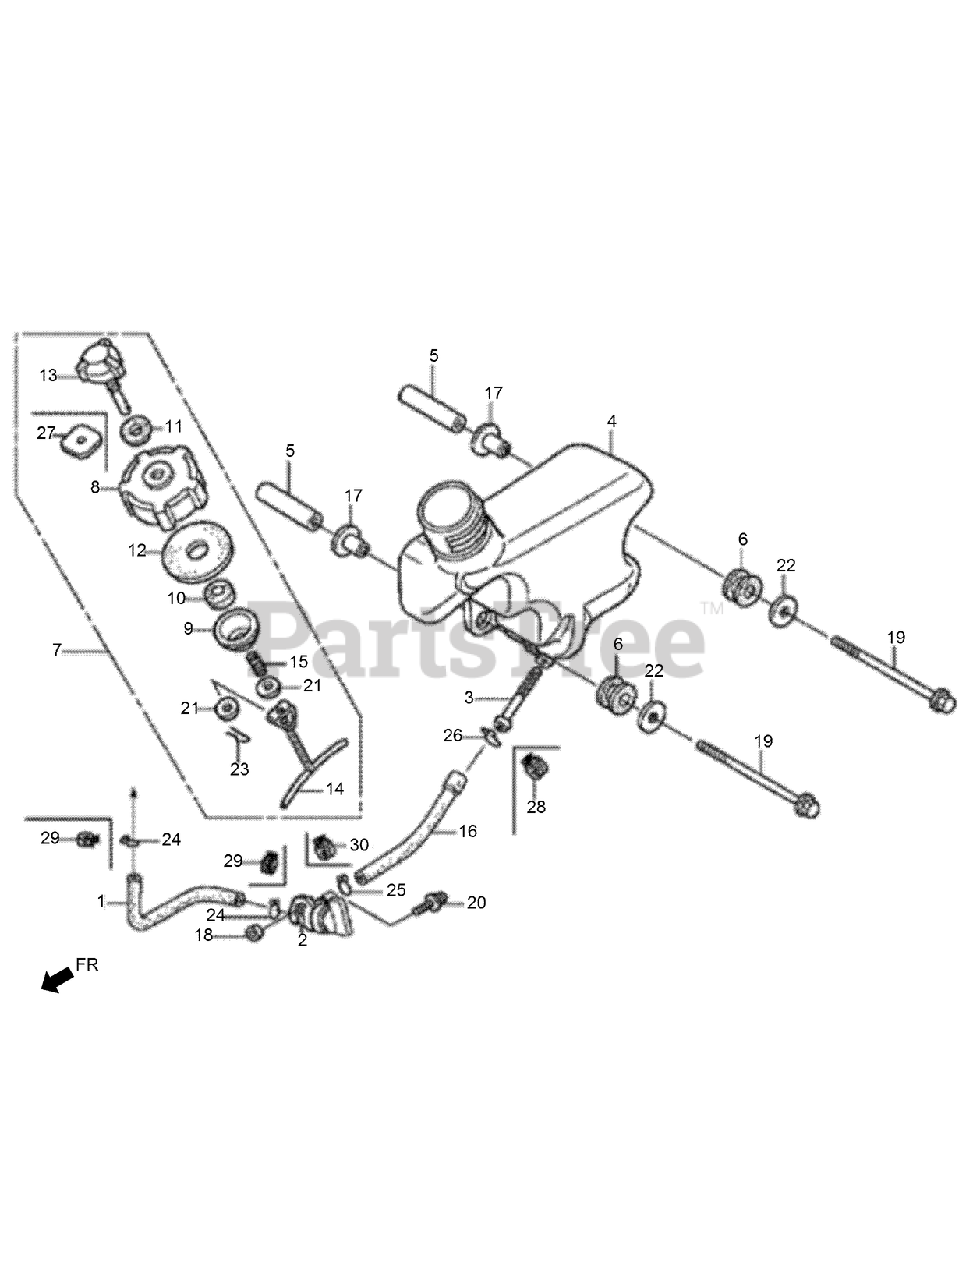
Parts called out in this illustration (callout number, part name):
1	TUBE B-FUEL
2	COCK ASM-FUEL
3	STRAINER-FUEL
4	TANK-FUEL
5	COLLAR-TANK SETTING
6	RUBBER A-TANK MOUNTING
7	CAP ASM-FUEL TANK
8	BODY-FUEL CAP
9	INNER-FUEL CAP
10	SPONGE-FUEL CAP BREATHER
11	PACKING-VALVE
12	PACKING-FUEL CAP
13	BREATHER VALVE ASM
14	LINK-FUEL CAP
15	SPRING-FUEL CAP
16	TUBE-FUEL
16	TUBE-FUEL TANK
17	COLLAR-CANISTER MOUNTING
18	COLLAR-FR WINKER
19	BOLT-FLANGE-6X65
20	SCREW-WASHER-5X10
21	WASHER-PLAIN-4MM
22	WASHER-PLAIN-6MM
23	PIN-LOCK-4MM
24	CLIP-TUBE
25	CLIP-TUBE
26	CLIP-TUBE
27	PACKING-VALVE
28	CLAMP-TUBE
29	CLAMP-TUBE
30	CLAMP-TUBE
